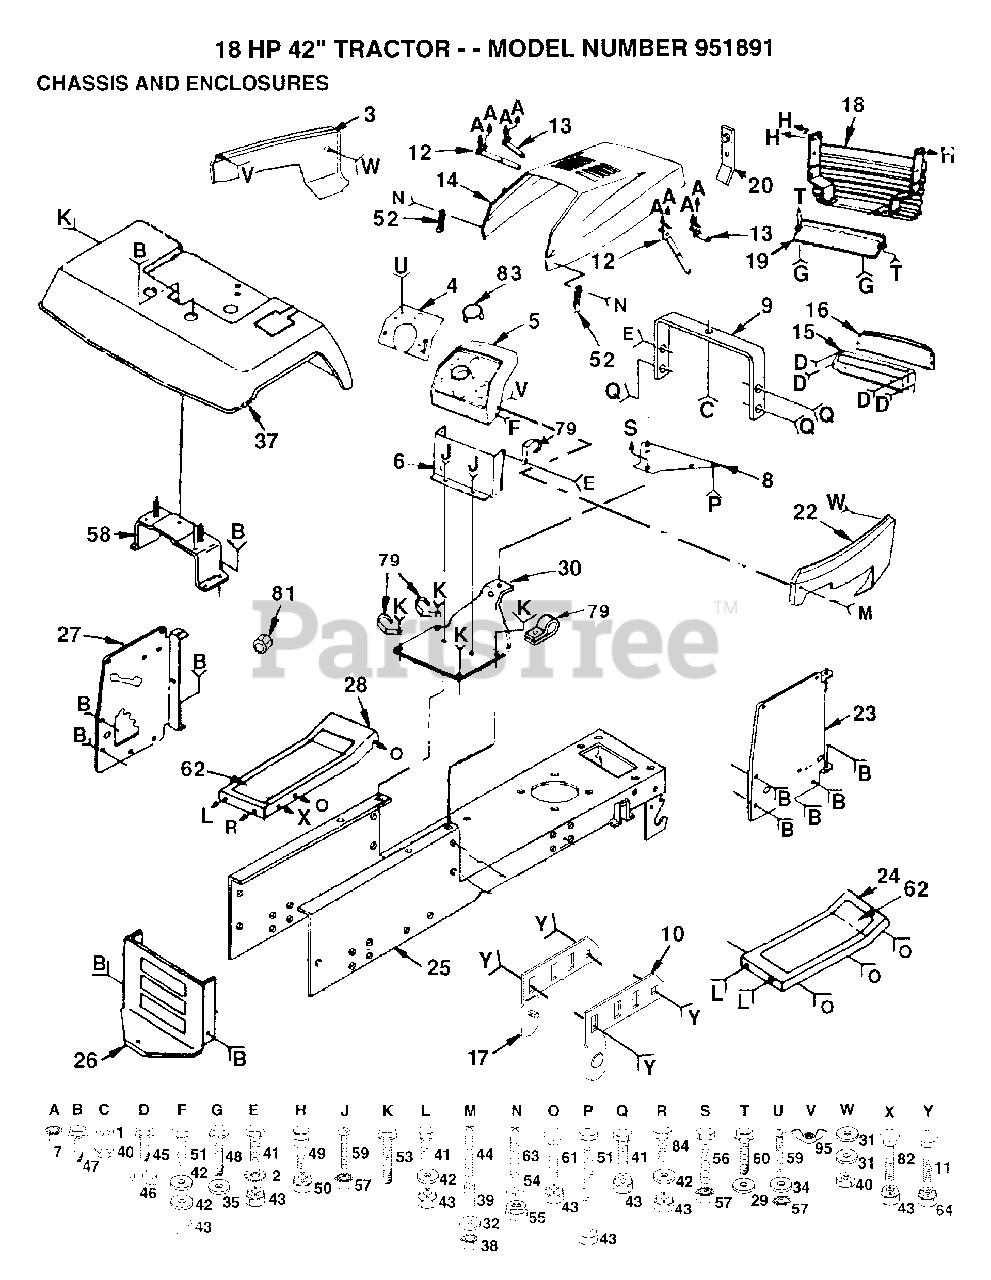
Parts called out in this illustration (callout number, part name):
1	LOCKWASHER
2	LOCKWASHER
7	NUT
9	SUPPORT ASS'Y
10	PIVOT BRKT RH
16	LENS LT
17	PIVOT BRKT LH
27	DASH PANEL LH
29	WASHER
30	SADDLE.LT.GOOSE
31	WASHER PM
32	WASHER
34	WASHER
35	WASHER
39	SPACER LT
42	WASHER
44	SCREW
46	"""J"" FASTENER LT"
47	SCREW
48	SCREW
52	HOOD LATCH T
53	SCREW LT
54	LOCKWASHER
55	WELDNUT
56	BOLT
58	BRKT FENDER
59	SCREW
60	SCREW HEX CRT
61	BOLT
62	FOOTREST PAD
63	SCREW
64	NUT
79	CLIP T
80	BOLT
83	PLUG DOME
